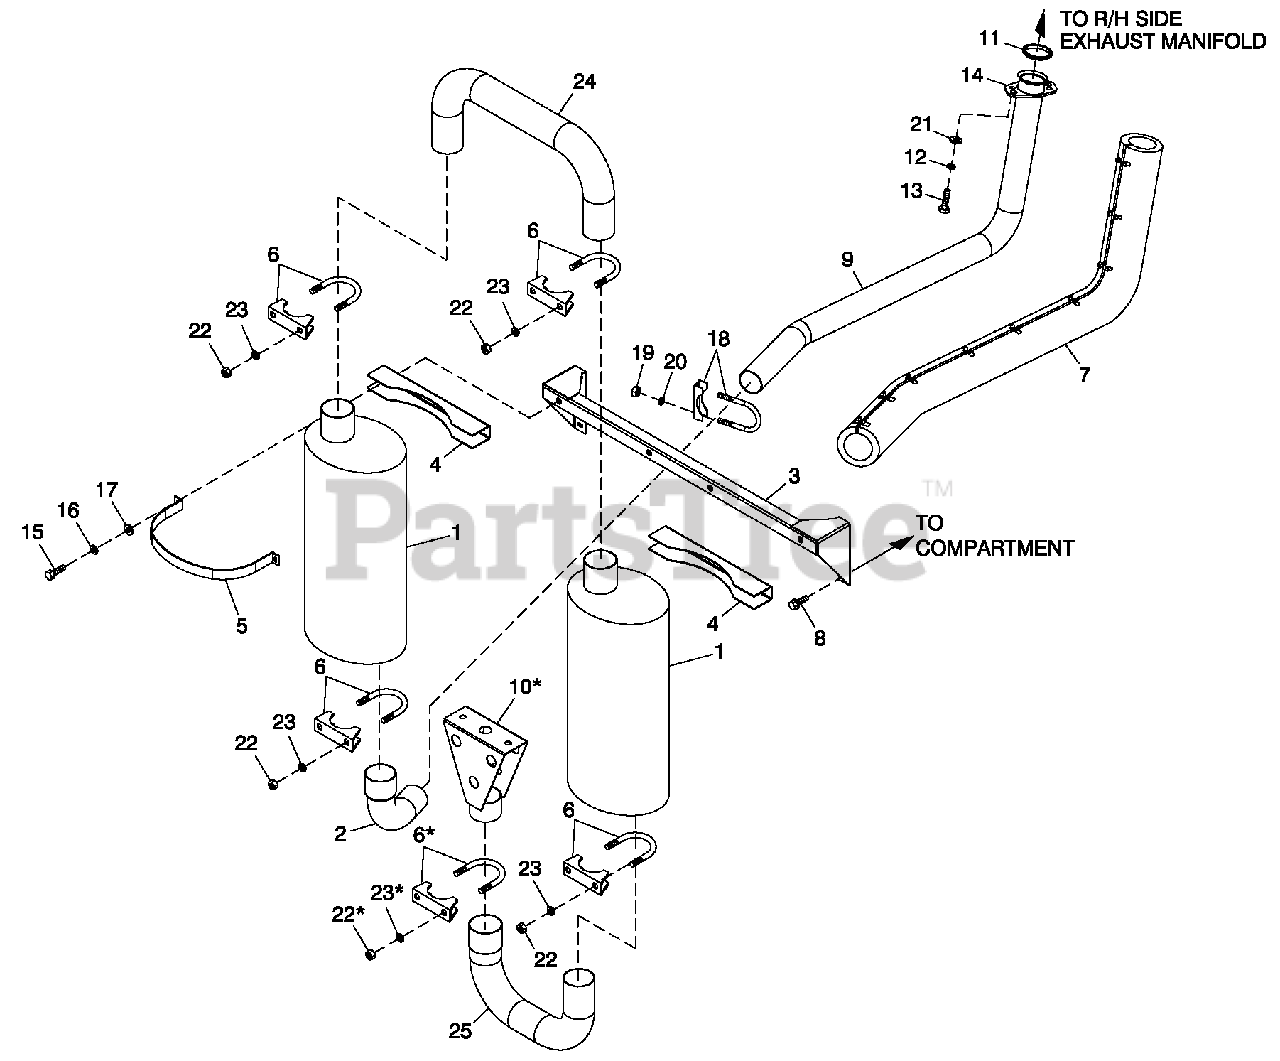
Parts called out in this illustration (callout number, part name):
1	REAR WRAP C2 G2 60KW
2	SCREW THF M6-1 X 16 N WA Z/JS
3	DOOR C2
4	RIVET POP.1875 X .450 SS
5	SCREW TH-FRM M6 W/CAP SHKPRF W
6	DUCT DSCHRG LH&RH
7	FRONT CORNERS C2
8	DUCT DISCHARGE C2
9	NUT HEX M6X1.0 G8 YELCHR
10	NUT HEX LOCK M6-1.0 SS NY INS
11	ROOF C2
12	SLITTER C4
13	SPLITTER LOWER C4
14	SPLITTER STINGER C2
15	SUPPORT SPLITTER LHC2
16	PULL TAB DOOR LOCK SS
17	ASSEMBLY COVER ACCESS
18	WASHER FLAT 1/4-M6 ZINC
19	WASHER LOCK M6-1/4
20	NUT HEX 1/4-20 STEEL
21	INSULATION RETAINMENT HANGER
22	WASHER SELF LOCKING DOME #4-40
23	SCREW HHFC M6-1.0X20 G8.8
24	KIT INSULATION C2
24A	INSULATION DOOR C2
24B	KIT INSULATION C2
24BA	INSULATION ROOF TOP
24BB	INSULATION ROOF TOP
24C	INSULATION SPLITTER
24D	INSULATION SPLITTER
24E	INSULATION LOWER SPLITTER
25	VISE-ACTION LATCH SLOTTED CIR
26	GASKET EXTRUDED TRIM (328" LG)
27	NUT UM6-1.0 GEOMET
28	RF COVER PLATE-PLASTIC-BISQUE
29	INSULATION DUCT
30	RETAINER INSULATION (820)
31	INSULATION DUCT SIDES
32	RETAINER INSULATION (450)
33	WASHER SELF LOCKING DOME #8-32
34	FOAM 300 X 300 THERMAL ACO
35	SCREW HHC M6-1.0X20 G8.8
36	ASSY WIRE 14AWG GRN/YEL
37	WASHER SHAKEPROOF INT 1/4
38	DEFLECTOR INTAKE 2.4L G2 TURBO
39	KEY VISE-ACTION LATCH SLOT CIR
40	TAPE FOAM 1X1 (71.0"LG)
41	STRIP SEALANT 1/8X 1 (44.52"LG)
